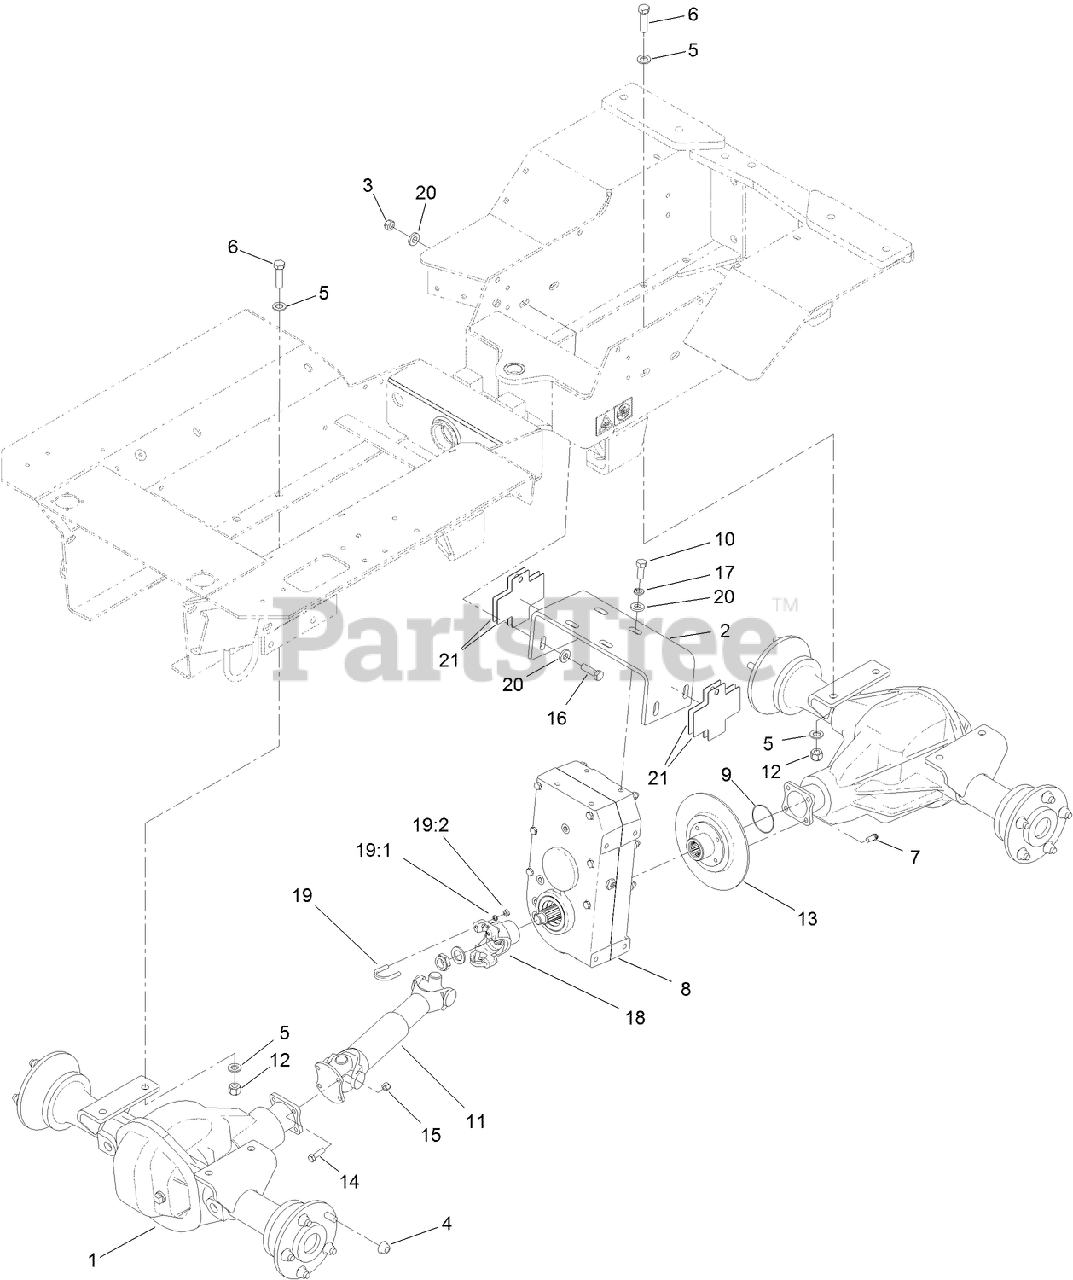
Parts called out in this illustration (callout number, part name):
1	AXLE-DRIVE
2	BRACKET-MOUNTING
3	LOCKNUT
4	NUT-HHF
5	WASHER-FLAT
7	SCREW-12 PT FLANGE
8	TRANSMISSION ASM
9	O-RING, SAE
10	SCREW-HH
11	DRIVE SHAFT ASM
12	NUT-HEX
13	FLANGE-COMPANION
14	SCREW-HH
15	NUT-HEX
16	SCREW-HH
17	WASHER-LOCK
18	YOKE-TRANSMISSION
19	BOLT-U (2 PER PACK)
19:1	NUT-HEX
19:2	WASHER-LOCK
20	WASHER-HARDENED
21	SHIM-BRACKET
